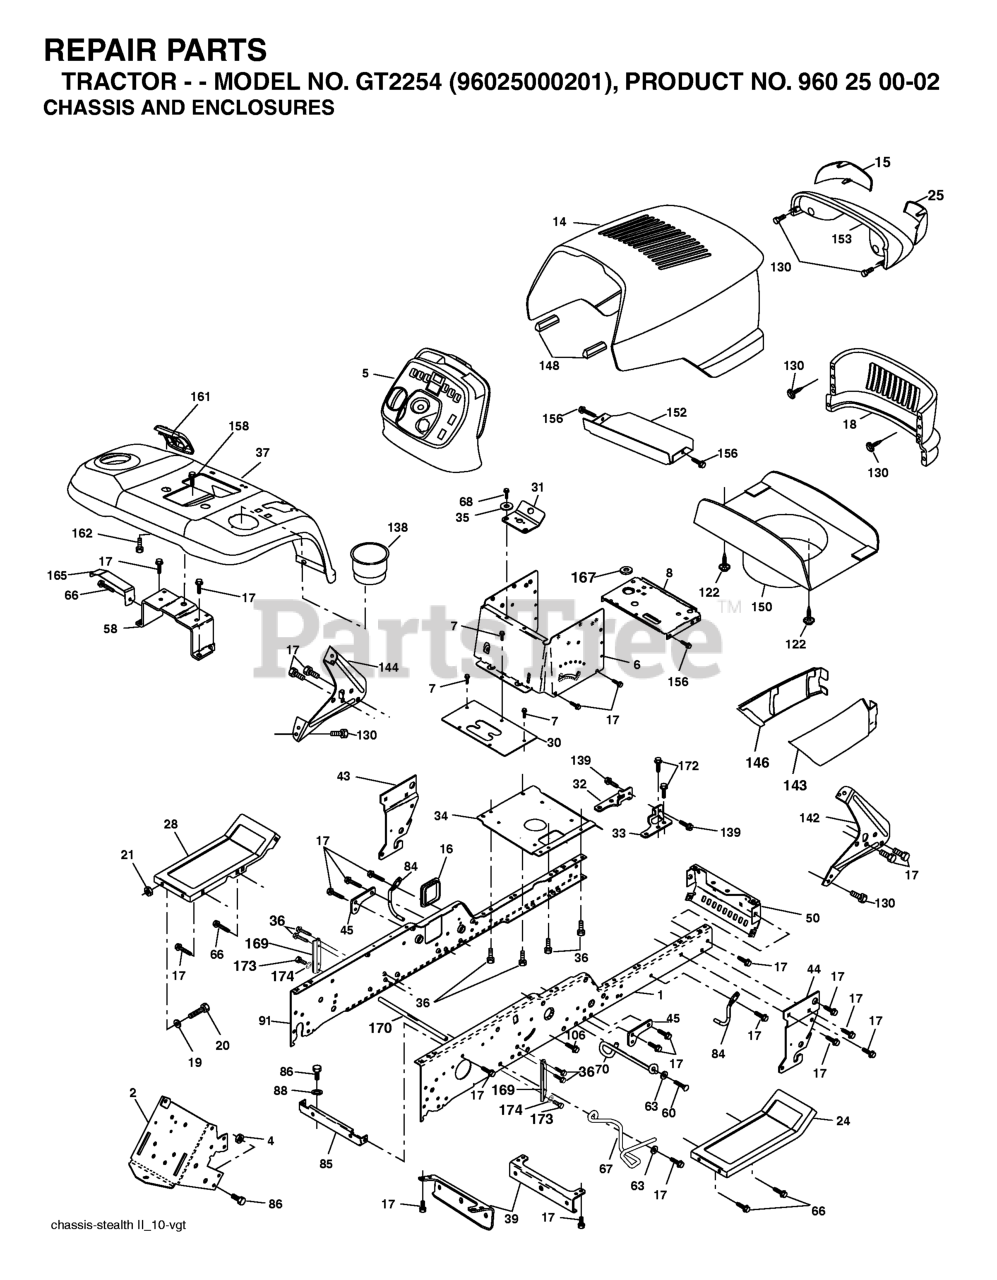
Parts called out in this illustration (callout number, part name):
1	KIT.RAIL.CHASS.RH.GT
2	DRAWBAR, GT
4	Nut, Crownlock Hex 7/16-14 unc
5	DASH STEALTH
6	DASH VGT, LOWER
7	SCREW
8	SUPPORT, BATTERY
14	HOOD
15	LENS LH
16	COVER ACCESS
17	SCREW, 3/8-16X3/4
18	GRILLE.STEALTH P/L.YTGT.GREY
19	WASHER
21	NUT
24	FOOTREST PNT RH
25	LENS RH
28	FOOTREST PNT LH
31	BRACKET SUPT 1-PC VGT STEERING
34	PLATE ASM ENG CHASSIS
35	WASHER
36	SCREW 5/16"
37	FENDER.PNT.YTGT.WO/SHF.ORANGE
39	BRACKET AXLE, FRONT
43	FRONT SUSPENSION BRKT LH
44	FRONT SUSPENSION BRKT RH
45	BRACKET ARM SUSPENSION
50	BRACKET, CHASSIS FRONT
58	BRACKET ASM., FENDER
60	SCREW.3/8-16
63	WASHER
68	Screw 5/16-18 x 1/2 Hex, Self Tapping 5/16-18 x 1/2
70	GUIDE.BELT.MID.SPAN.54"
84	UPSTOP 54"
85	BRKT.SUPPT
86	BOLT FIN HEX 7/16-14 X 1
88	LOCKWASHER
91	KIT.RAIL.CHASS.LH.GT
106	BOLT.5/16-18X1.25
122	SCREW.WSHD.HEX10-32X5/8
130	SCREW
137	BOLT FIN HEX 7/16-14 X 1
138	CUPHOLDER.YTGT
139	BOLT, SHOULDER 5/16-18
142	BRACKET DASH STEALTH(R)
143	SKIRT GRILLE RH
144	BRACKET DASH STEALTH LH
146	SKIRT GRILLE LH
148	EXTRUSION BUMPER (3 2) (2 2)
150	DUCT.HEAT.HOOD.STEALTH.GT
152	BROWNING SHIELD
153	LIGHTBOX.ASM.STV.DL.INC.HUSQ
156	SCREW
158	SCREW 3/8-16X1/2
161	CONSOL.FUEL.WINDOW.BLACK
162	SCREW.HI-LO.CONSOLE
165	BRACKET SUPPORT TANK
169	BRACKET CHASSIS SWAY
170	ROD.BRKT.SWAY
171	BUSHING SNAP
172	SCREW 3/8-16X.875
173	BOLT.FIN.HEX.5/16-18X3/4
174	WASHER.LOCK.HVY.HLCL.SPR.5/16
